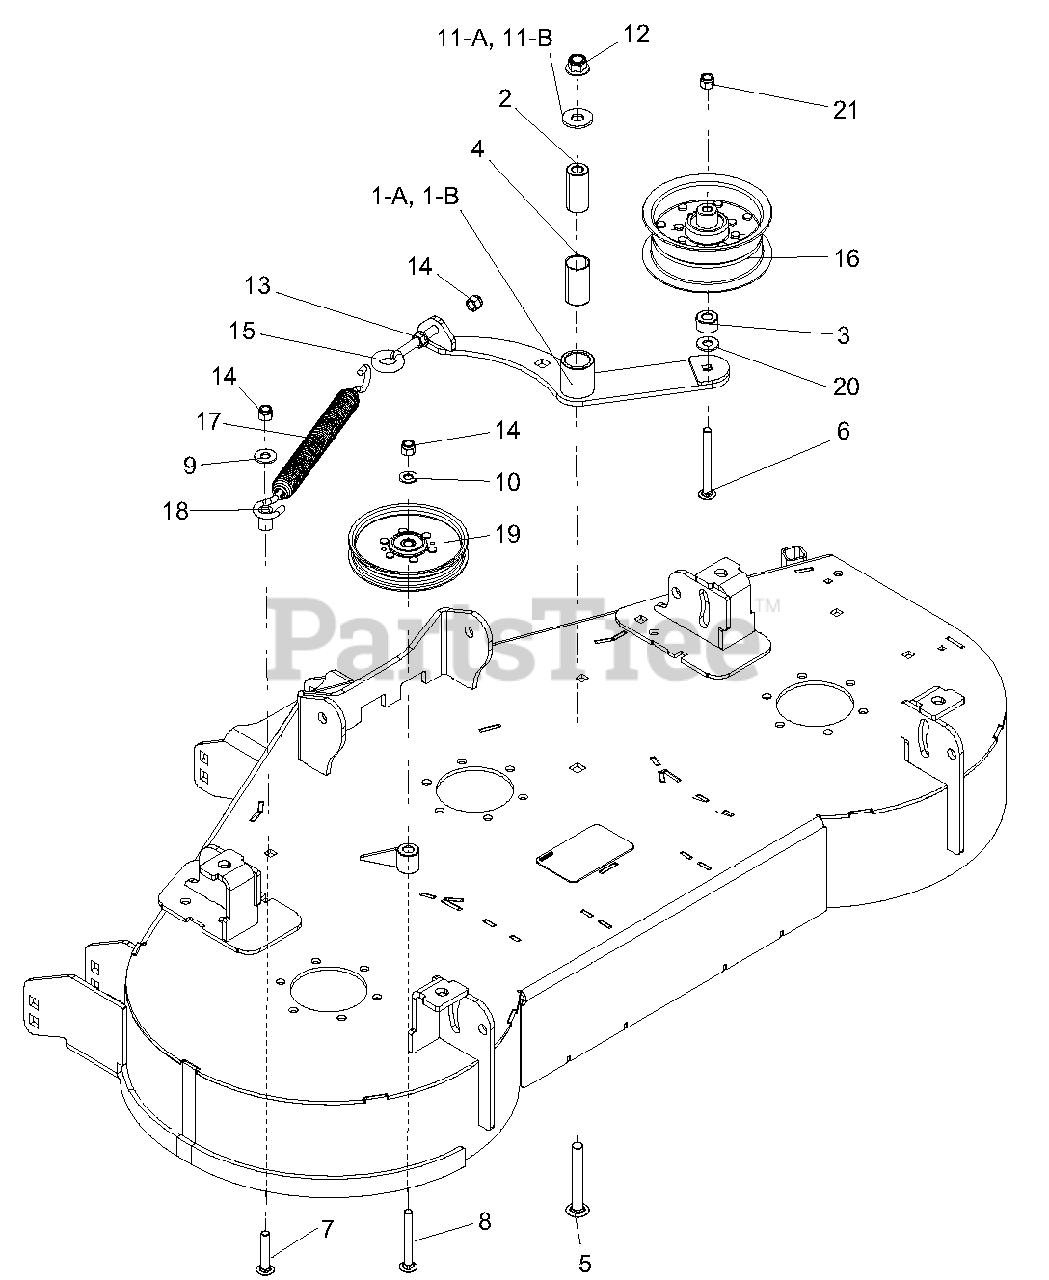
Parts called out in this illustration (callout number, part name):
1-A	WLDMT, IDLER PROSTANCE (994111,112,113,117,118)
1-B	WLDMT, IDLER PROSTANCE (994114,115)
2	BSHG, SPCR .502 X .997 X 2.03
3	SPACER, .437 X 1.00 .58 SMLS
4	BSHG, 1.00 X 1.125 X 1.937
5	BLT-RHDSSQNK .50-13 X 3.50 G5YZ
6	BLT-RHDSSQNK .38-16 X 3.50 G5YZ
7	BLT-RHDSSQNK .38-16 X 2.00 G5YZ
8	BLT-RDHDSQNK .38-16 X 3.00 G5 YWZC
9	WSHR-FL-STL .438 X 1.00 X .083 YWZC
10	WSHR-FL-STL .406 X .812 X .065 YWZ
11A	SPACER, IDLER ARM (994111,112,113,117,118)
11B	WSHR-FL-STL .563 X .138 X .109 YWZC (994114,115)
12	NUT-LK-CTR .50-13 YWZC
13	NUT-SPNLK-FLG .375-16 YWZC
14	NUT-LK-NYL .38-16 YWZC
15	BOLT, EYE .38-16 X 4.25 .62 DIA EYE
16	PULLEY, FLAT 5.00 X 2.36 X .375
17	SPRG, EXTENSION
18	BUSH, S.391X.622X.95 ST REV A
19	PULLEY, FLAT 5.00 X .375 W/BRG
20	WSHR-FL-STL .406 X 1.00 X .188 YWZ
21	NUT-LK-NYL-FLG .38-16 YWZC
